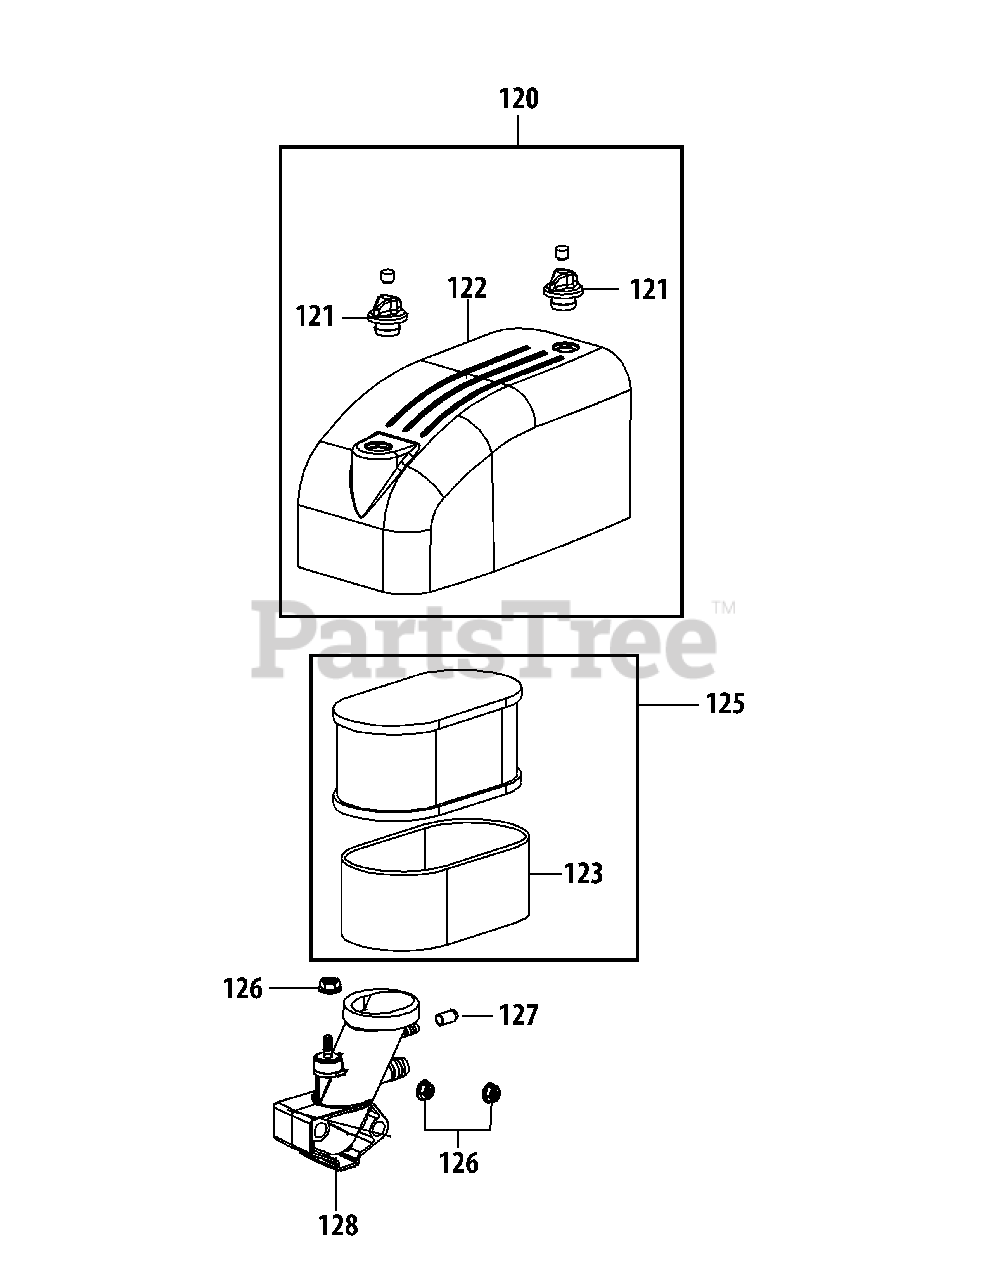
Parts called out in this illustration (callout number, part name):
120	Air Filter Cover Assembly
121	Air Filter Lock Nut
122	Air Filter Cover
123	Sponge Filter
125	Air Filter Assembly
125	Genuine Factory Parts AIR FILTER
126	Nut M6
127	Rubber Cap
128	Manifold
